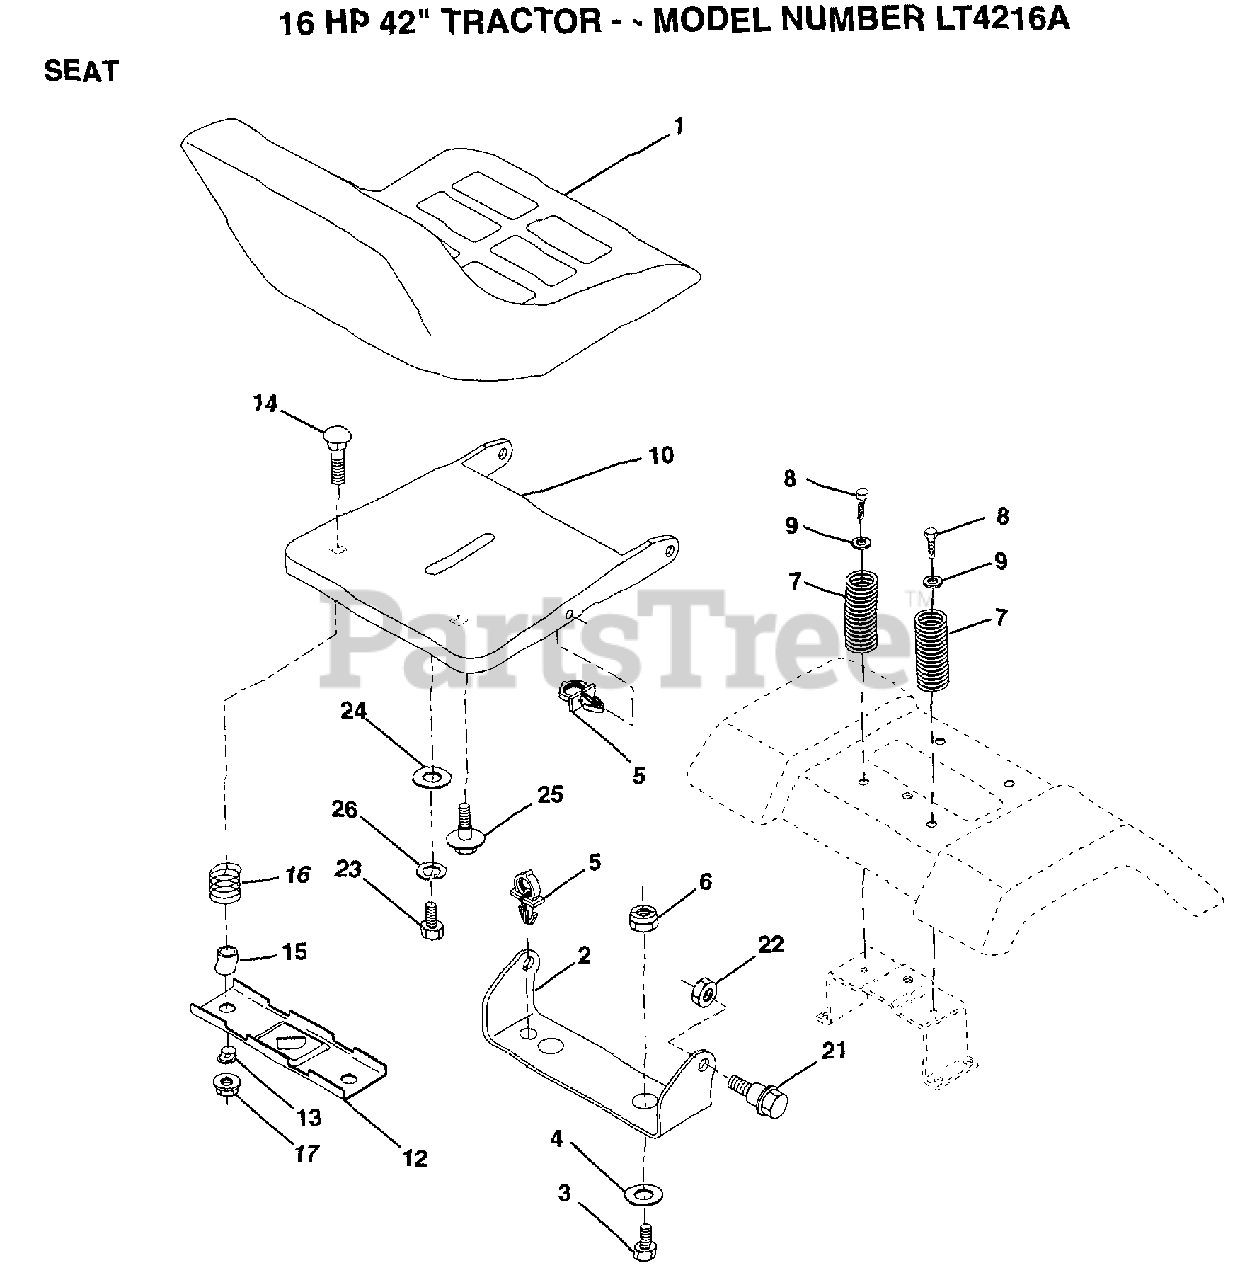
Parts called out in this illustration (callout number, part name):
2	BRACKET PVT SEAT
3	BOLT
4	WASHER PM
5	CLIP PUSH - IN
6	NUT
7	SPRING COMPRESSIO
8	SCREW GTV
9	WASHER
12	BRKT SWITCH
13	BUSHING
15	SPLIT SPACER
16	SPRING
21	BOLT.SHLD.5/16-18
22	NUT
23	BOLT
24	WASHER
25	"BOLT,SHOULDER"
26	LOCKWASHER
